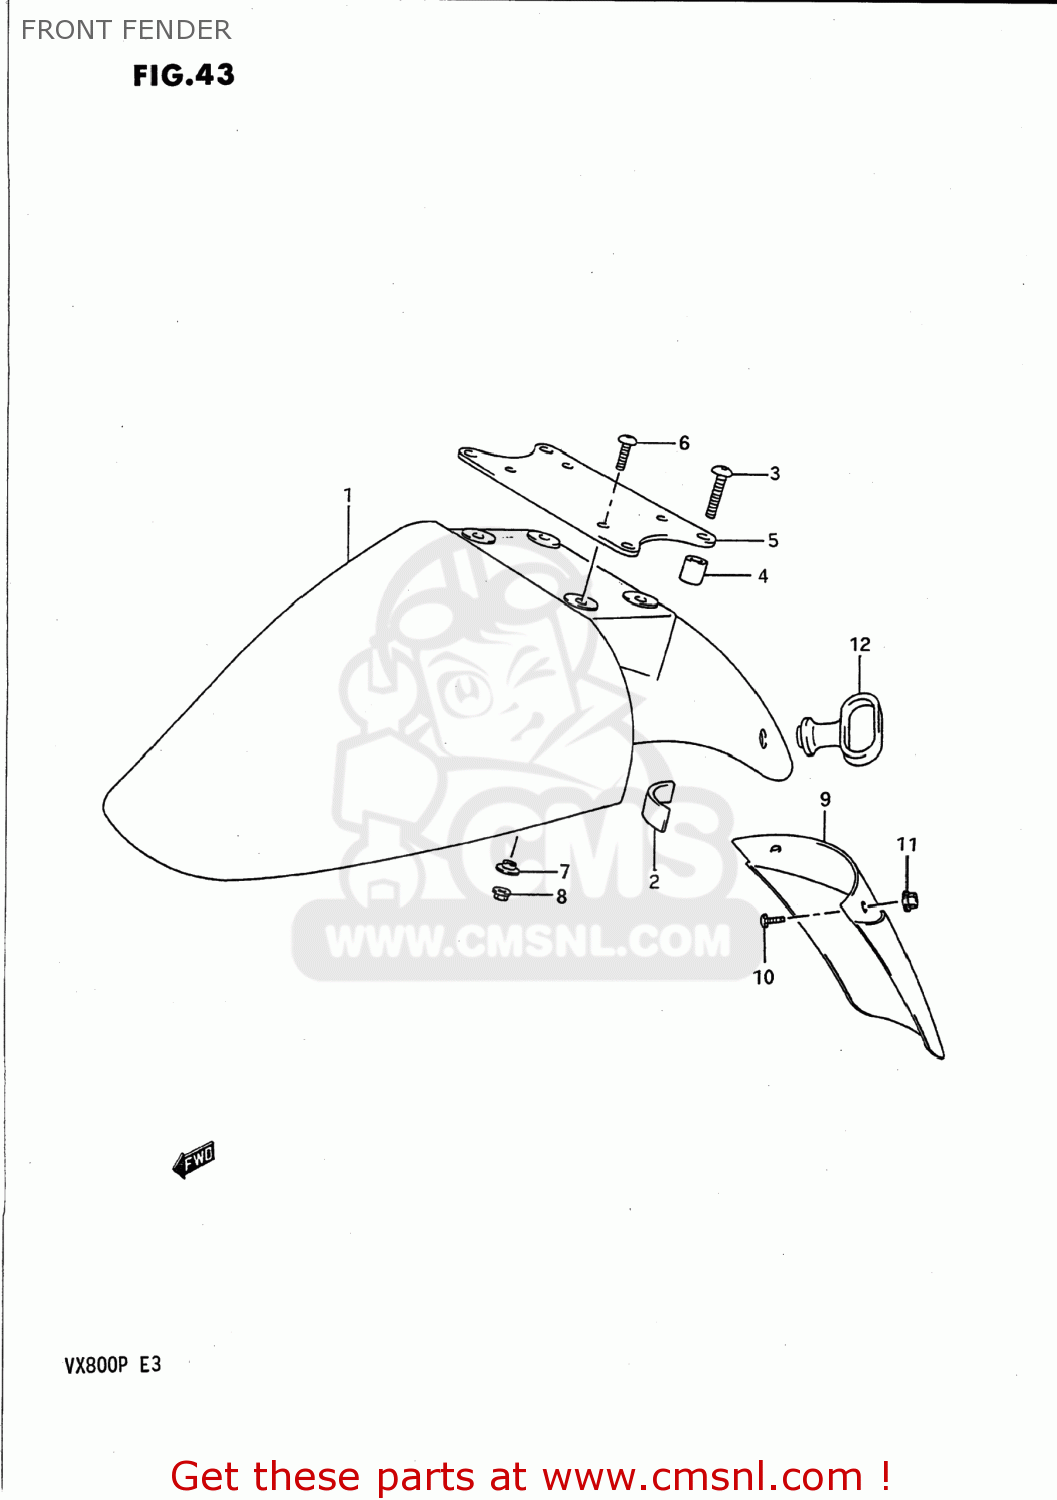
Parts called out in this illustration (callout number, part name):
1	FENDER,FRONT
2	CUSHION,BODY COWLING
3	SCREW(6X30)
4	SPACER (6.5X11.5X15.5)
5	BRACE,FR FENDER
6	SCREW(5X16)
7	WASHER
8	NUT
9	EXTENSION,FR FENDER
10	SCREW
11	NUT 5MM
12	GUIDE,CABLE
